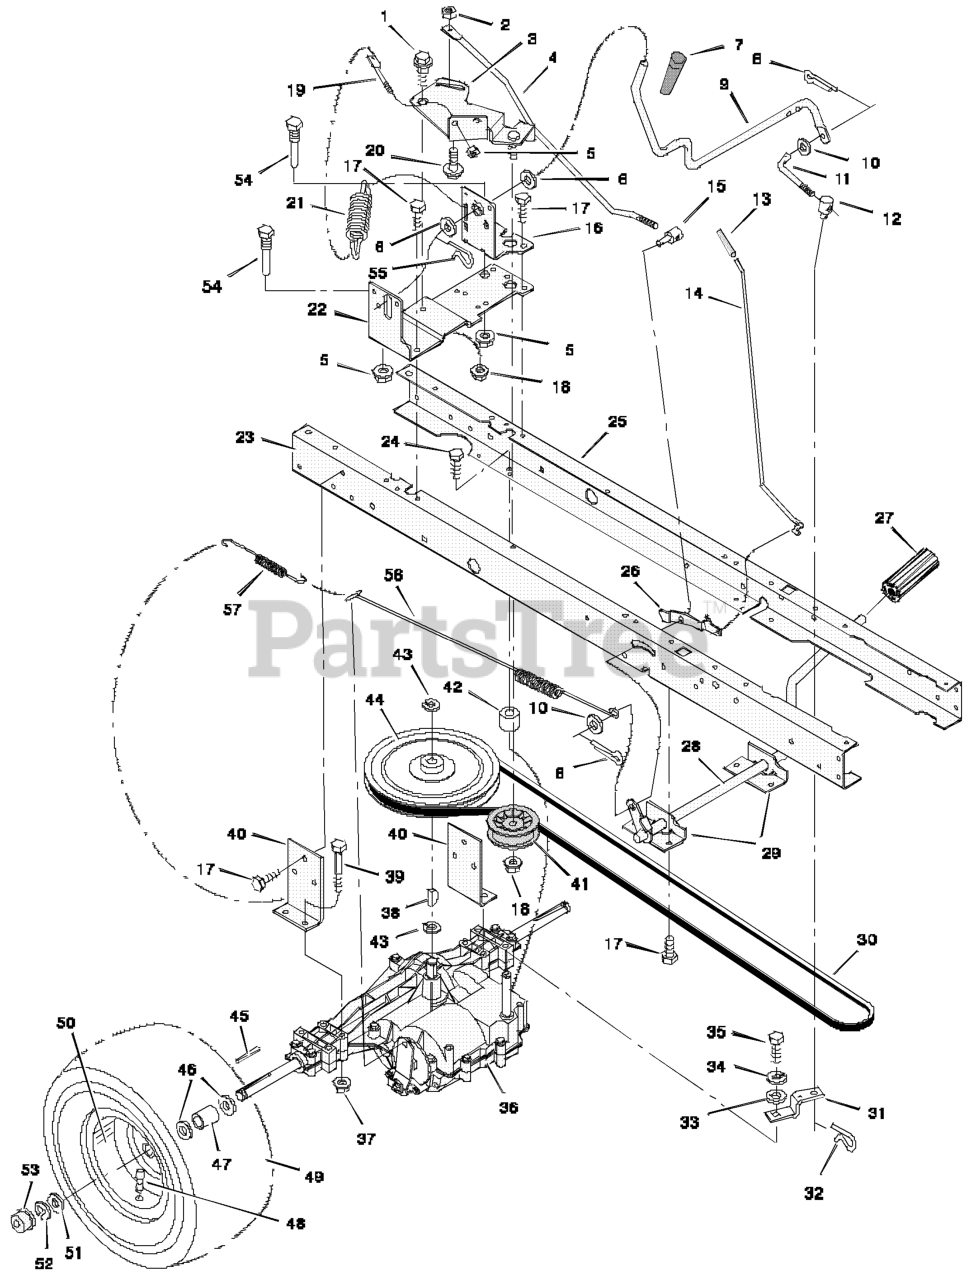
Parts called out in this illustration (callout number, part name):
1	Bolt, Shoulder
2	Nut, Hex
3	Arm, Idler
4	Rod, Clutch
5	Nut
6	Washer
7	Grip
8	Pin, Cotter
9	Lever, Shift
10	Washer
11	Link, Shift
12	Nut, Adjuster
14	Rod, Parking Brake
15	Nut, Adjuster
16	Bracket, Shift
18	Nut
20	Bolt, Shoulder
21	Spring, Extension
22	Bracket, Shifter
23	Frame, Right
25	Frame, Left
26	Latch, Parking Brake
27	Pedal
28	Lever, Brake/Clutch
29	Bracket, Pedal
30	Belt, Motion Drive
31	Yoke, Shift
32	Pin, Hair
34	Washer
36	Transaxle **
37	Nut
38	Key, Woodruff
40	Bracket, Transaxle
43	E- Ring
44	Pulley, Drive
45	Key, Square
47	Spacer, Transaxle
48	Stem, Valve
50	Wheel & Tire Assembly
53	Hub Cap
54	Guide, Belt
55	Pin, Hair
56	Spring, Extension
57	Spring, Extension
